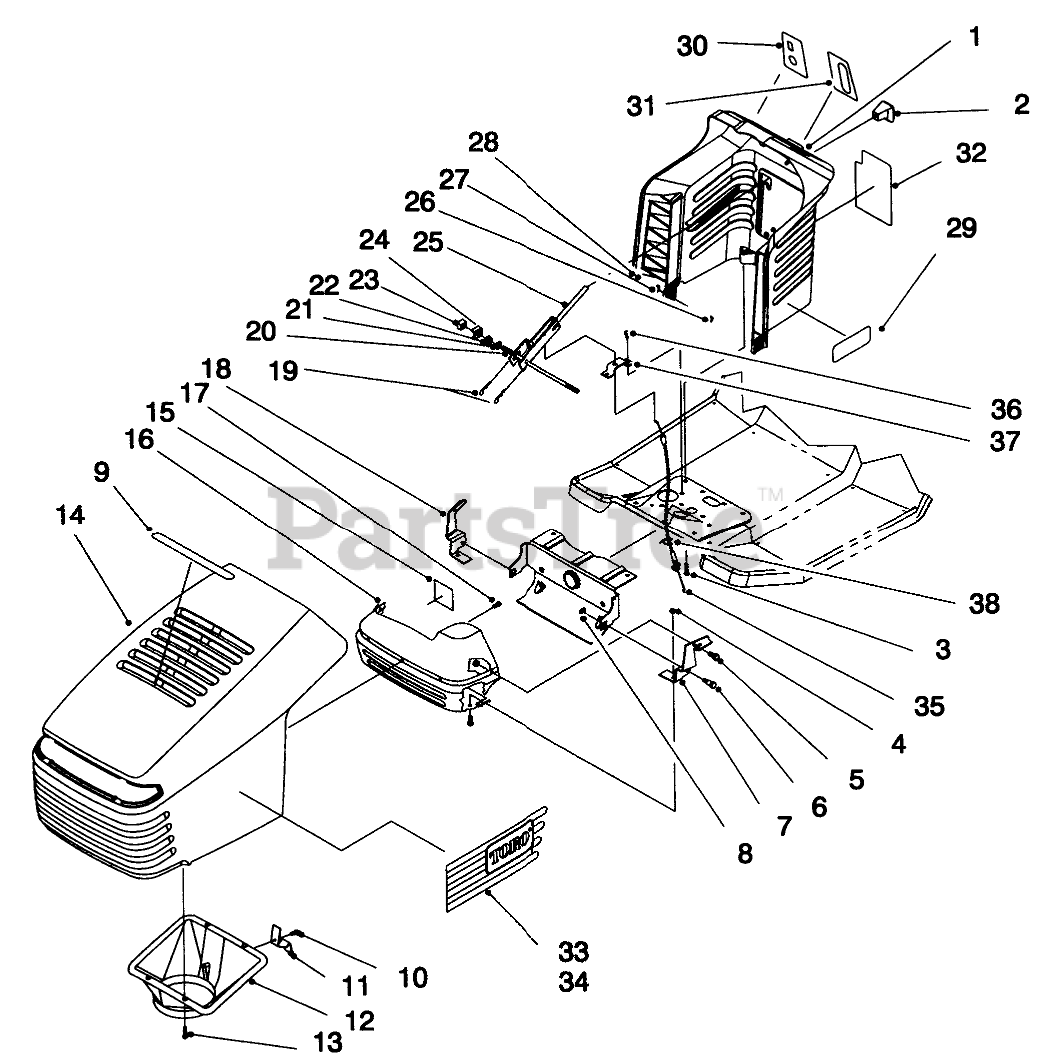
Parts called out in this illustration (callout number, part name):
1	Tower-Steering
2	SHIFT KNOB
3	SCREW-HWH
4	NUT-LOCK, NI
5	SCREW-HH
6	BOLT-SHOULDER
7	Bracket-Hinge L.H.
8	NUT-RETAINER
9	DECAL-AIR DUCT
10	SCREW-PLASTITE
11	HOOD LATCH
12	DUCT-AIR, HOOD
13	SCREW-PLASTITE
14	HOOD ASM
15	TAPE-FOIL
16	Shield-Heat
17	SCREW-PLASTITE
18	Bracket-Hinge R.H.
19	PIN-COTTER
20	ROD-TOWER PIVOT
21	WASHER-FLAT
22	NUT-FLANGE
23	NUT-WEDGE
24	ROD-CLAMP PIVOT
25	Lever-Deck Engage
26	NUT-LOCK, NI
27	WASHER-PLAIN
28	SCREW-HH
29	DECAL - TOWER, 1544 HXL
30	DECAL-IGNITION/LIGHTS
31	DECAL
31	DECAL-THROTTLE/CHOKE
32	DECAL-DECK, ENGAGE
33	DECAL - HOOD LEFT
34	DECAL - HOOD RIGHT
35	CABLE, DECK ENGAGE
36	SCREW-HWH
37	BRACKET-CABLE, UPPER
38	TIE-CABLE
